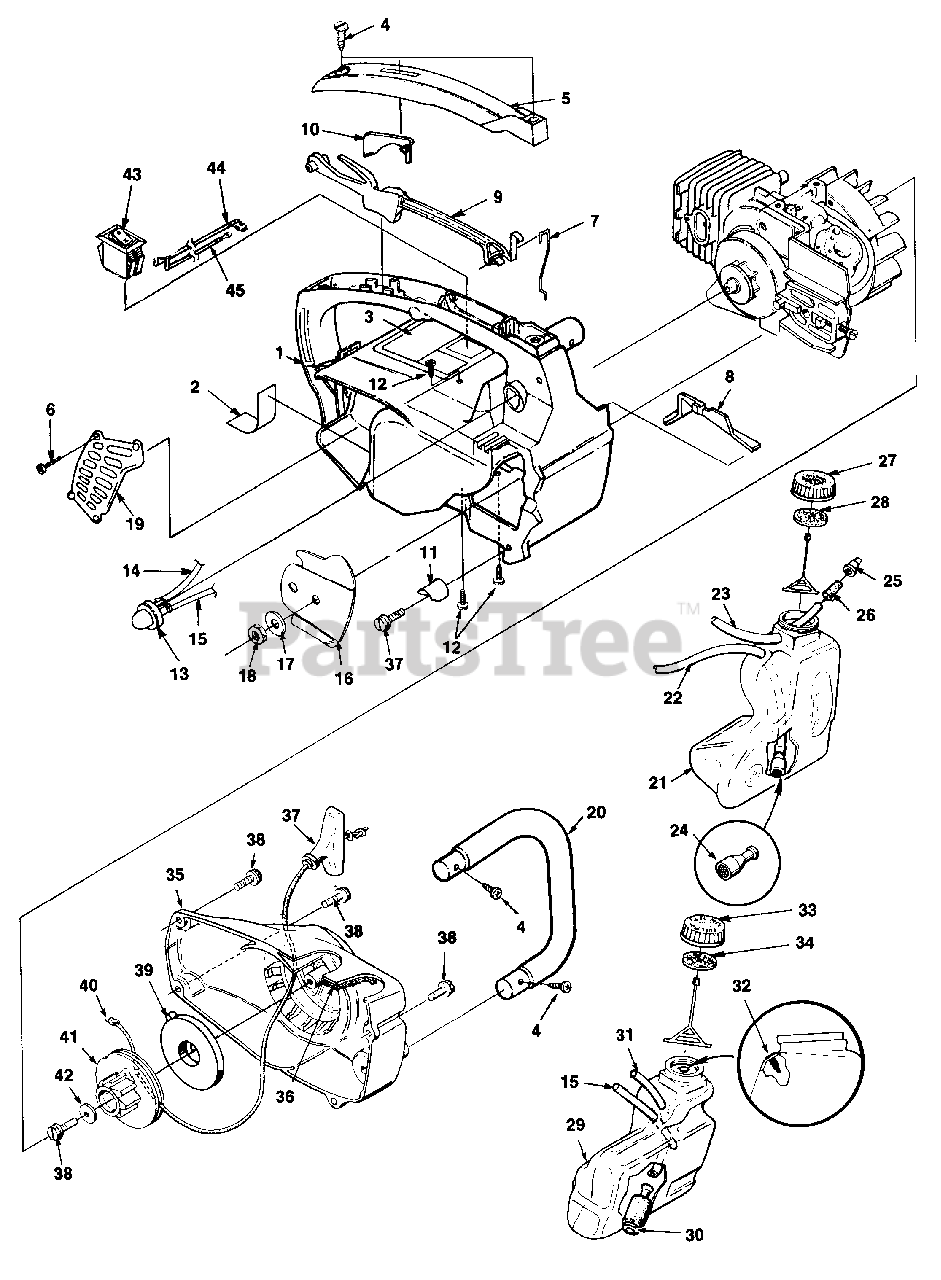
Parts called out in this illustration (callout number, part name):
1	HOUSING- Engine
2	TAPE
4	SCREW- Pan, plastite (#10-16 x 3/4")
5	COVER- Handle
6	SCREW- Pan plastite (#6-3/8")
7	ROD- Throttle
8	COVER- Air filter
9	TRIGGER
10	LOCK- Trigger
11	STOP- Chain
12	SCREW- Torx, taptite (#10-24 x 3/4")
13	PRIMER BULB
14	TUBING- Inlet (3")
15	TUBING- Return (7")
16	PLATE- Guide bar
17	WASHER- Flat
18	NUT- Hex
19	SHIELD- Muffler
20	HANDLE BAR
21	TANK- Oil
22	TUBING- (9")
23	TUBING (4 3/4")
24	FINDER- Oil
25	VALVE- Check
26	FITTING- Oil line
28	GASKET- Cap
29	TANK- Fuel
30	FILTER- Fuel
31	LINE- Fuel (5 1/2")
32	VALVE- Check
33	CAP- Fuel
34	GASKET- Cap
35	STARTER HOUSING ASSY.
37	GRIP- Starter
38	SCREW- Torx, plastite (#10 x 3/4")
39	SPRING & CONTAINER
40	ROPE- Starter
41	PULLEY- Starter
42	WASHER- Retaining
43	SWITCH
44	LEAD- w/Flag Term.
45	LEAD- w/Ring Term.
